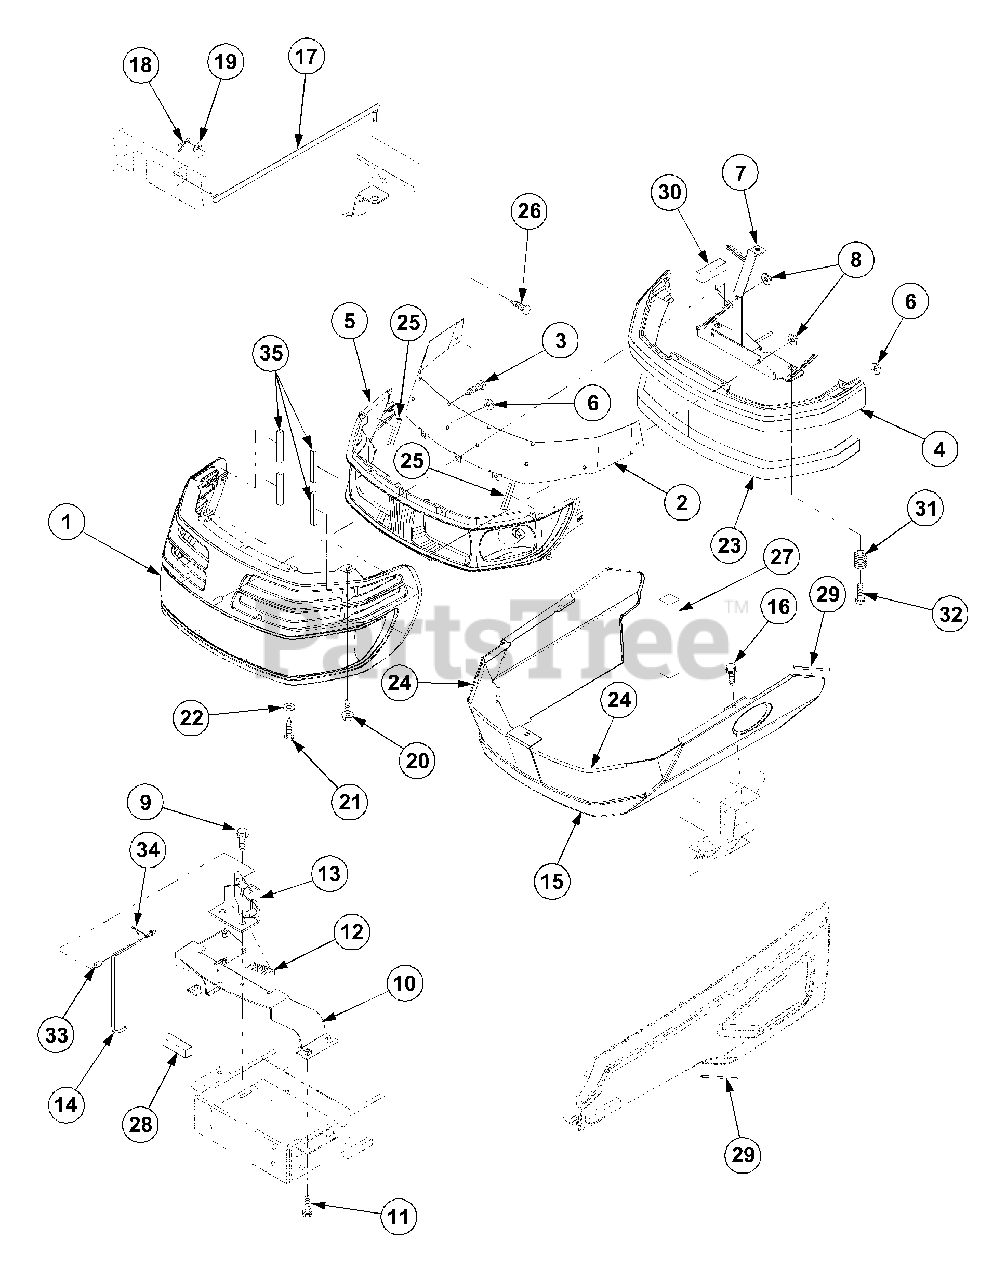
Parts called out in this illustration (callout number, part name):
3	Screw,Tapping
7	Bracket
9	Bolt,w/Washer
11	Bolt,w/Washer
13	Bracket
16	Bolt,w/Washer
18	Pin,Split
20	Bolt,w/Washer
21	Screw,Tapping
24	Rubber,Cushion
34	Pin,Split
